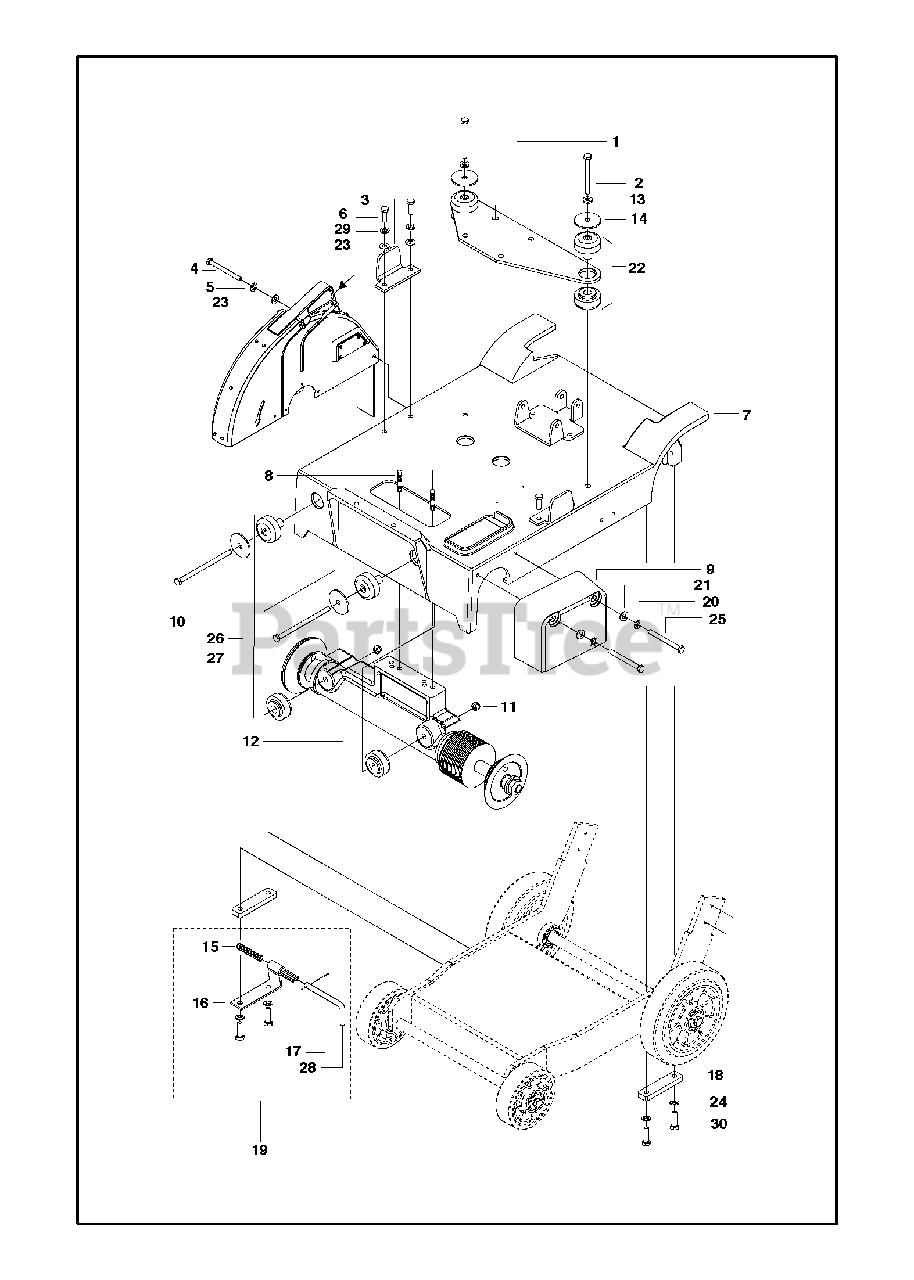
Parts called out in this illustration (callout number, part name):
5	SPRING WASHER
10	HHCS. M10X1.5X130MM Z/P
11	HEXAGON LOCKING NUT
20	SPRING WASHER
21	WASHER
23	WASHER
24	SPRING WASHER
29	SPRING WASHER
